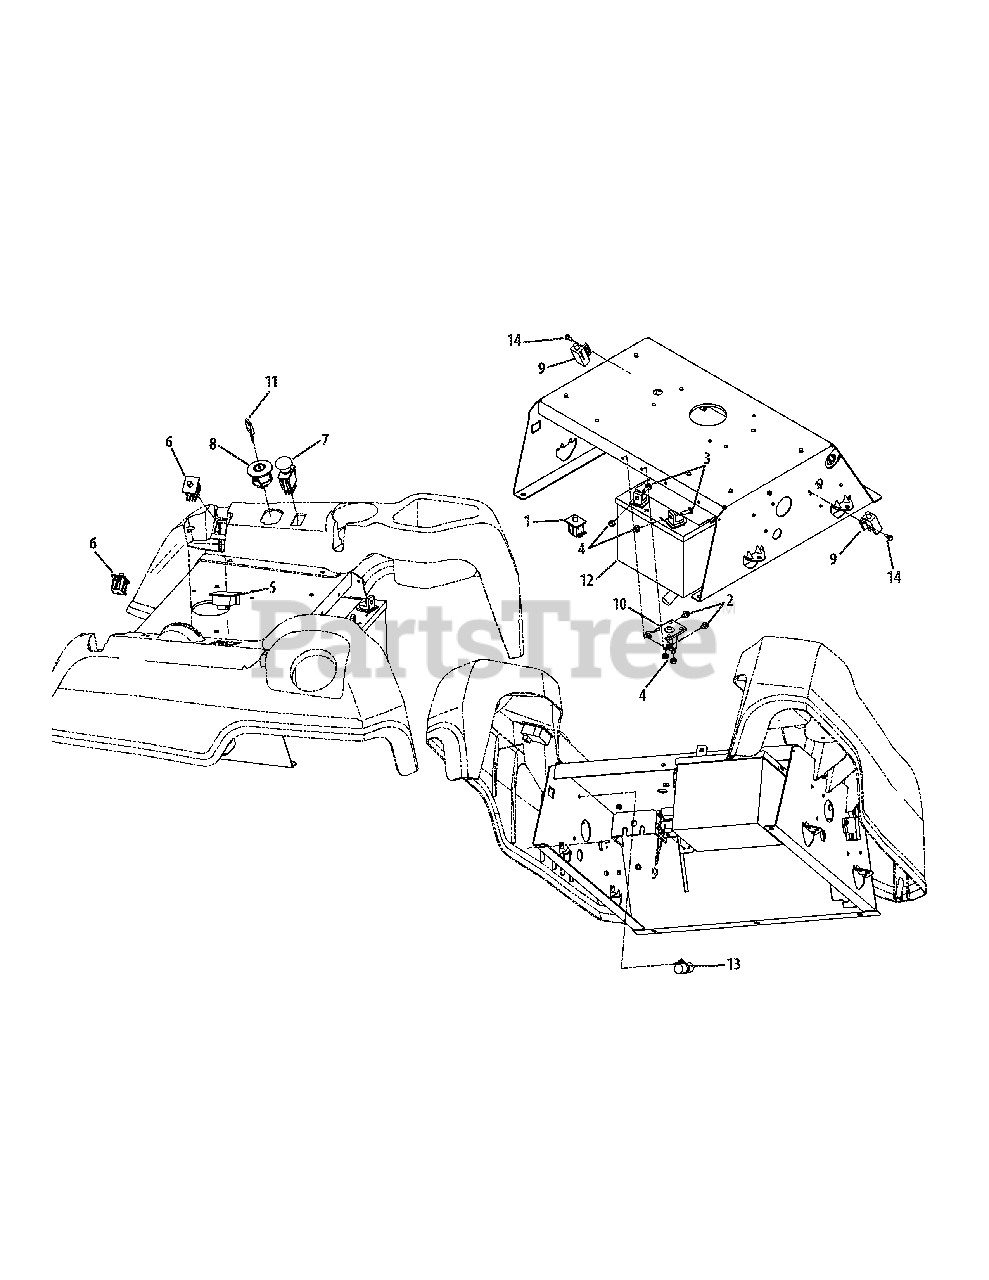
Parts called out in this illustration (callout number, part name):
1	Seat Switch
2	Hex Washer Screw, 1/4-20 x .375
3	Hex Screw, 1/4-20 x .75
4	Hex Nut, 1/4-20
6	Double Pole Neutral Switch
7	PTO Switch
8	Ignition Switch
9	Brake/Reverse Interlock Switch
10	Solenoid
11	Key
13	Cable Tie
14	Shoulder Screw, #10-32 x .5
